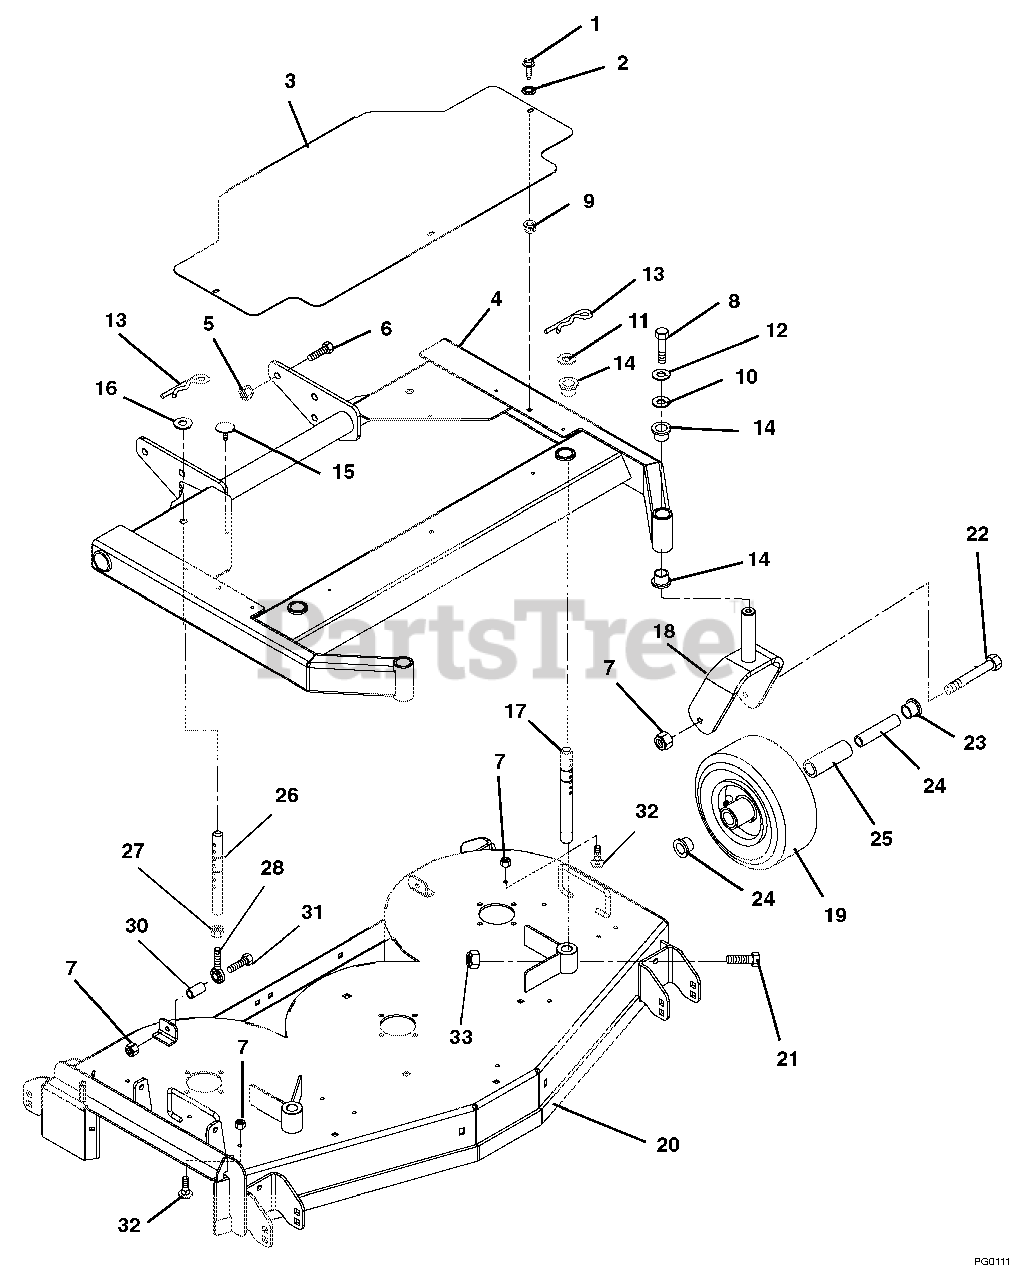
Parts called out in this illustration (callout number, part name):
1	SCR-TAP .25-20X.50 HWH TR YWZ
2	@WSHR-FL-STL.281X.62X.065 YWZC
3	COVER- BELT PRO 48 FLOATING
4	WMT-MOWER FRAME- 48" FLOAT
5	@NUT-LK-NYL .625-11 YWZC
6	@BLT-HEX .62-11X1.50 GR5 YWZC
7	@NUT-LK-TOP-FLG .38-16 YWZC
8	@BLT-HEX .38-16X1.25 GR5 YWZC
9	GRMT,PLASTIC
10	WSHR-FL-STL .380X1.50X.125YWZC
11	WSHR-FL-STL .890X1.500X.1196YZ
12	@WSHR-LK .38X.094 REG YWZC
13	PIN-HAIR-INT .17X.68X3.50 YWZC
14	BSHG-FLG 1.00X1.25X1.50X1.50EP
15	BUMPER GROMMET
16	@WSHR-FL-STL.688X1.75X.134 YWZ
17	ROD- FRONT HEIGHT ADJUSTMENT
18	WMT - CASTER FORK
19	ASSY, WHEEL AND TIRE 9X3.5
20	KIT-48" FL MOWER DECK W/DECALS
21	@BLT-HEX .25-20X2.00 GR5 YWZC
22	BLT-HEX .38-16X5.50 YWZC
23	RTNR-BEARING-PRO
24	BEARING .625 X .380 X 4.08
25	BEARING, ROLLER--PRO
26	ROD- REAR HEIGHT ADJUSTMENT
27	NUT-JAM .375-24 YWZC
28	ROD END, 3/8 RH
30	@BLT-HEX .38-16X1.50 GR5 YWZC
31	ANCHOR, SPRING (RED)
32	@BLT-RDHDSQNK .38-16X.75 G5YZ
33	@NUT-LK-TOP-FLG .25-20 YWZC
